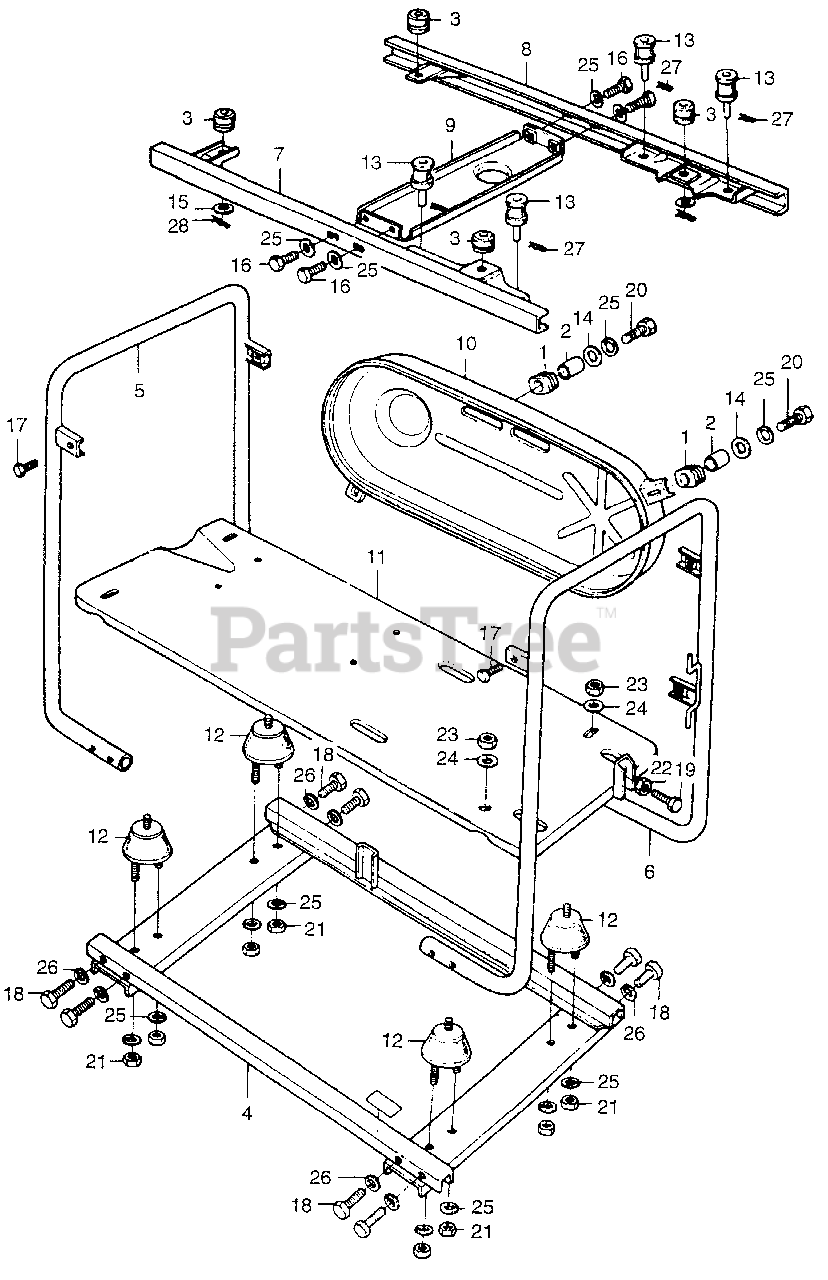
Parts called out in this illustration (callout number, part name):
1	RUBBER, TANK CUSHION
2	COLLAR B, TANK DISTANCE
3	RUBBER, TANK CUSHION
4	BED, FRAME
5	FRAME, L. SIDE
7	FRAME, FR. (UPPER)
8	FRAME, RR. (UPPER)
9	STOPPER, ENGINE
10	COVER, BELT *R8* (BRIGHT RED)
11	BED, ENGINE
12	RUBBER, ENGINE SETTING
13	RUBBER, TANK CUSHION (NOT AVAILABLE)
15	WASHER, FLAT (20MM)
16	BOLT, HEX. (6X12)
17	BOLT, HEX. (8X10)
18	BOLT, HEX. (8X20)
19	BOLT, HEX. (8X40)
20	BOLT, HEX. (6X20)
20	BOLT-WASHER (6X20)
21	NUT, HEX. (6MM)
22	NUT, HEX. (8MM)
23	NUT, HEX. (8MM)
24	WASHER, PLAIN (8MM)
25	WASHER, SPRING (6MM)
26	WASHER, SPRING (8MM)
27	PIN, LOCK (5MM)
28	PIN, LOCK (6MM)
